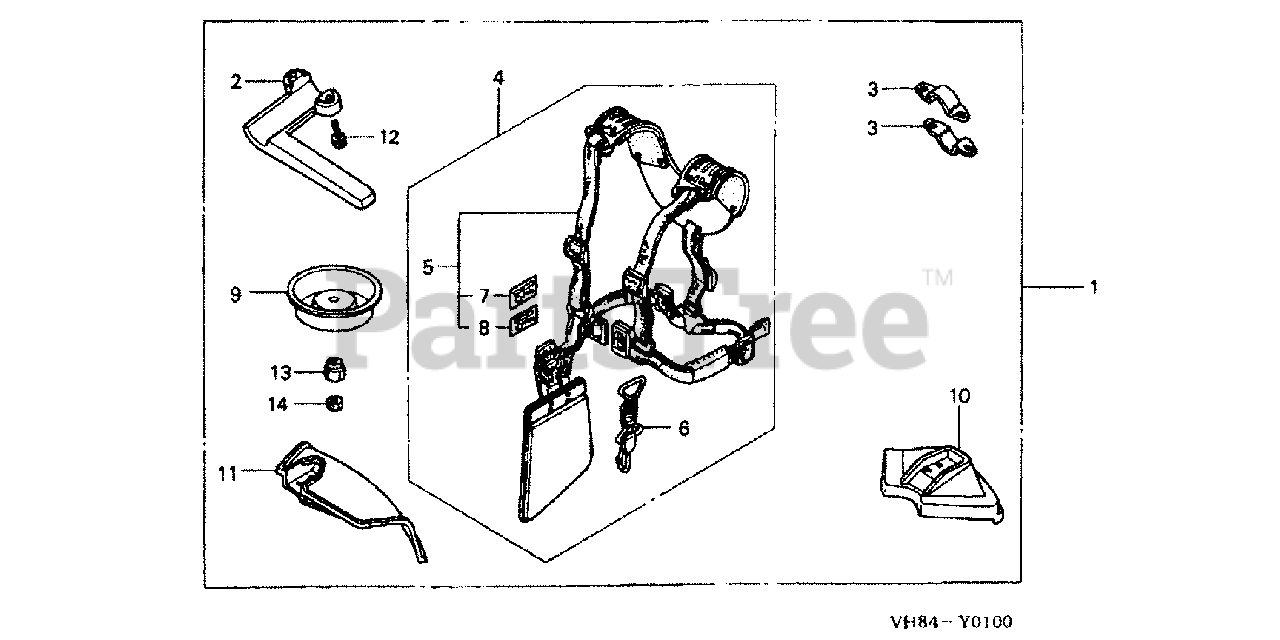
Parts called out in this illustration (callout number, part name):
1	BARRIER KIT
2	BAR, LOOP HANDLE
3	HOLDER, LOOP HANDLE
4	BELT ASSY., SHOULDER
5	BELT, SHOULDER
6	HOOK, SHOULDER BELT
7	MARK, QUICK RELEASE (E)
8	MARK, QUICK RELEASE (F)
9	COVER, NUT
10	DEFLECTOR, GRASS
11	DEFLECTOR, GRASS
12	BOLT, SOCKET (6X18)
13	NUT, LOCK (10MM)
14	NUT, HEX. (6MM)
